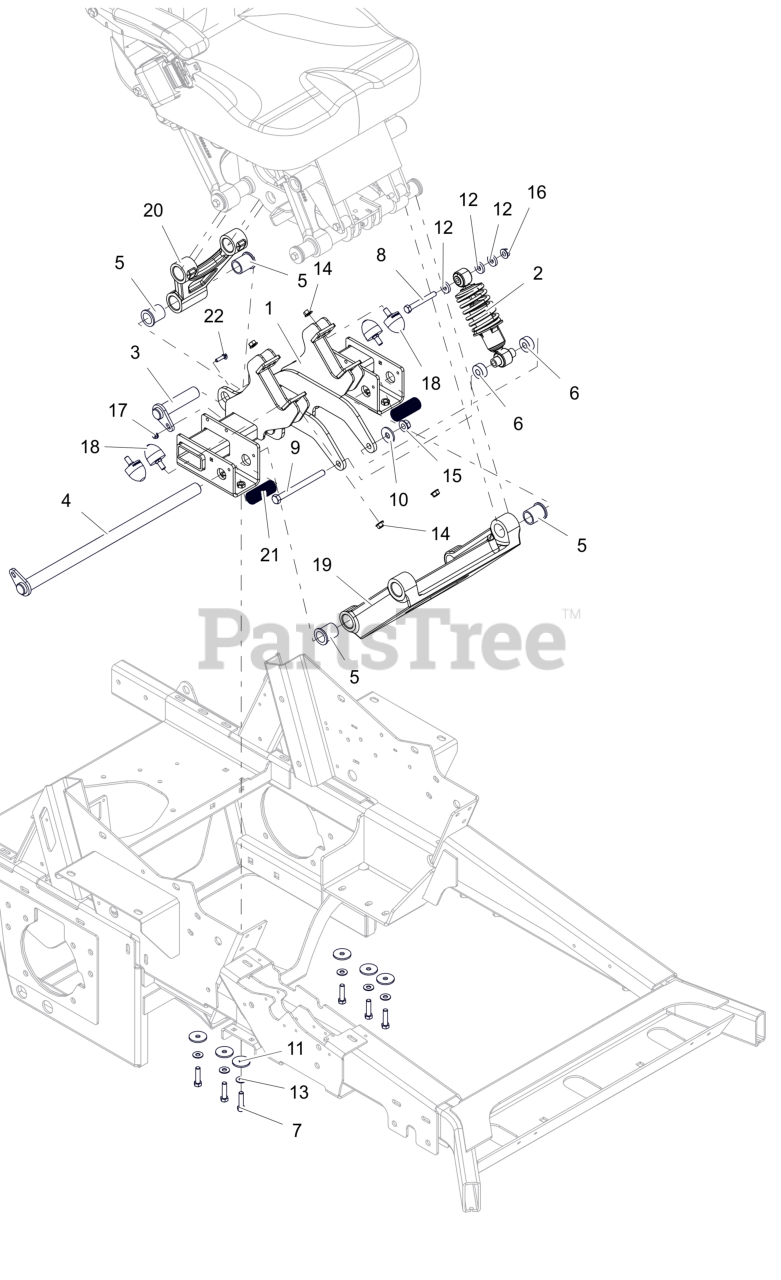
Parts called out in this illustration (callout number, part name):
1	WLDMT, SUSPENSION MTG (RED)
2	SHOCK, LOWER - TENNECO
3	WLDMT, LOWER REAR PIVOT SHAFT (RED)
4	WLDMT, LOWER FRONT PIVOT SHAFT (RED)
5	BEARING, SINTERED BRONZE FLANGE
6	SPCR, .400 x 1.250 x .513
7	BLT, HEX 0.375-16X1.5 GR8 ZCC
8	BLT,HEX M10-1.5X80 G10.9 ZCC
9	BLT,HEX M12-1.75X140 G10.9 ZCC
10	WSHR-FL-STL.511X1.44X.125ZC120
11	WSHR, FLT .380X1.50X.125 ZCC
12	WSHR, FLT .406X1.00X.188 ZCC
13	WSHR, HDND 0.375X0.875X0.064 ZCC
14	NUT-LK-CTR-FLG .375-16 GF ZCC
15	NUT, FLG-CTR LK M12-1.75 ZCC
16	NUT, FLG-CTR LK M10-1.50 ZCC
17	NUT-LK-CTR-FLG .25-20 ZC120
18	BUMPER, CONICAL
19	MACHINED, FRONT LOWER LINK
20	MACHINED, REAR LOWER LINK
21	SLEEVE, SHAFT
22	BLT, RHSN .25-20X1.00 G5 ZCC
